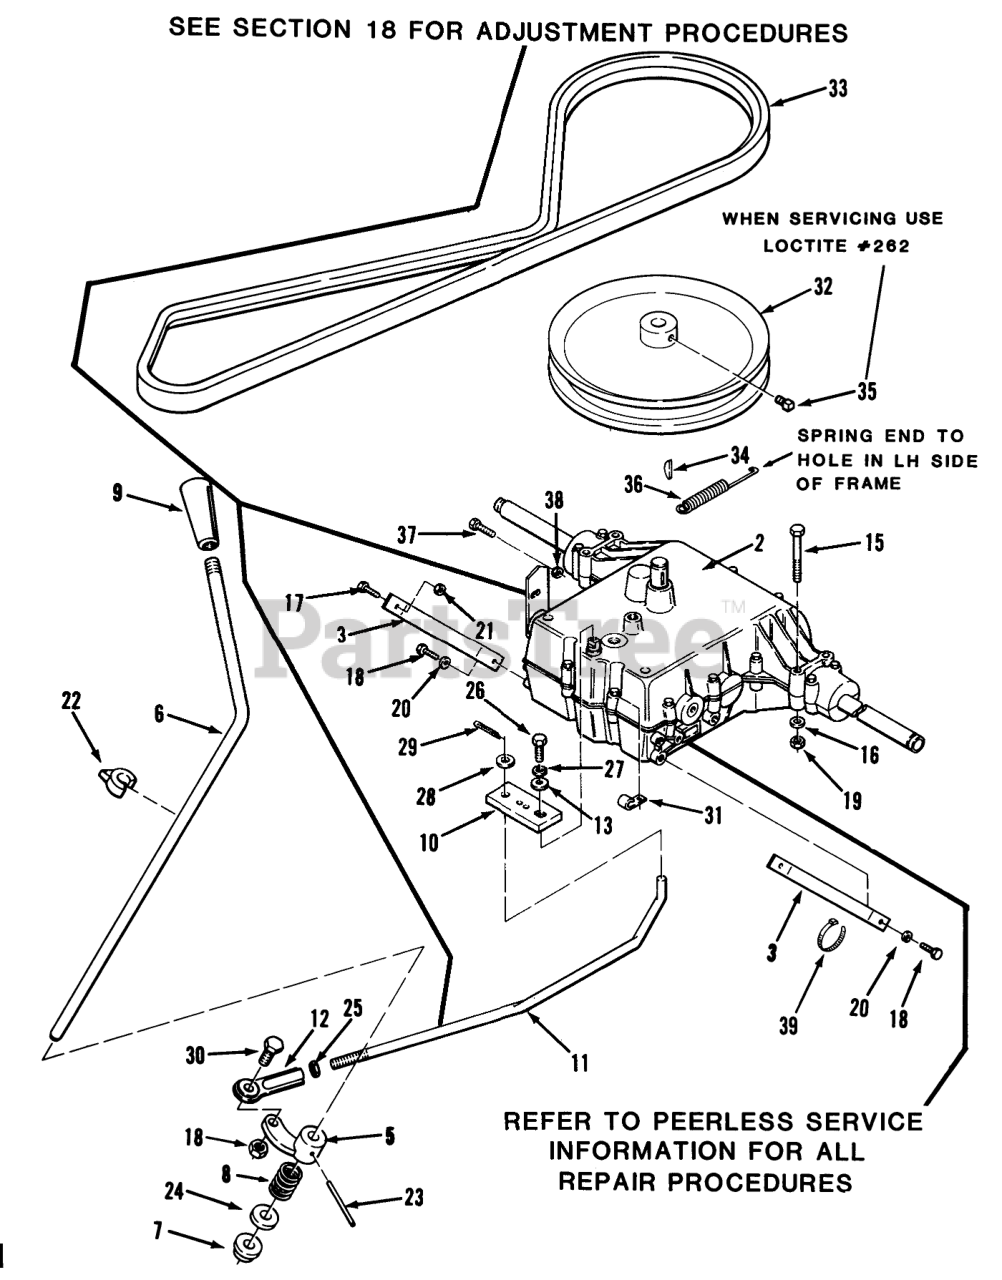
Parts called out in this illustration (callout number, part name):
2	Trans.-5-Spd.(Peerless Model 920-009)
3	TORQUE-STRAP R
5	ARM SHIFTER B
6	ROD-SHIFT LEVER
7	BUSHING-NYLINER
8	SPRING COMPRESSION
10	ARM-TRANSMISSION 5SP
11	ROD-LINKAGE
12	END-ROD
13	WASHER
15	HHCS
16	WASHER 5/16 SAE
17	CARRIAGE BOLT -4
18	Screw
19	Nut
20	Lockwasher
21	Nut
22	POINTER
23	SPIROL PIN 7/32X21/2
24	Washer
25	Nut
26	Hex Hd. Cap Screw 1/4-28 x 7/8
27	Washer
28	WASHER 5/16 SAE
29	Cotter Pin
30	BOLT-SPEC 5/16X1.25
31	J-CLIP
32	PULLEY-TRANS
33	BELT-V
34	KEY-HI-PRO
35	Set Screw
36	SPRING-EXTENSION
37	Bolt
38	Nut
39	PLASTIC TIE
